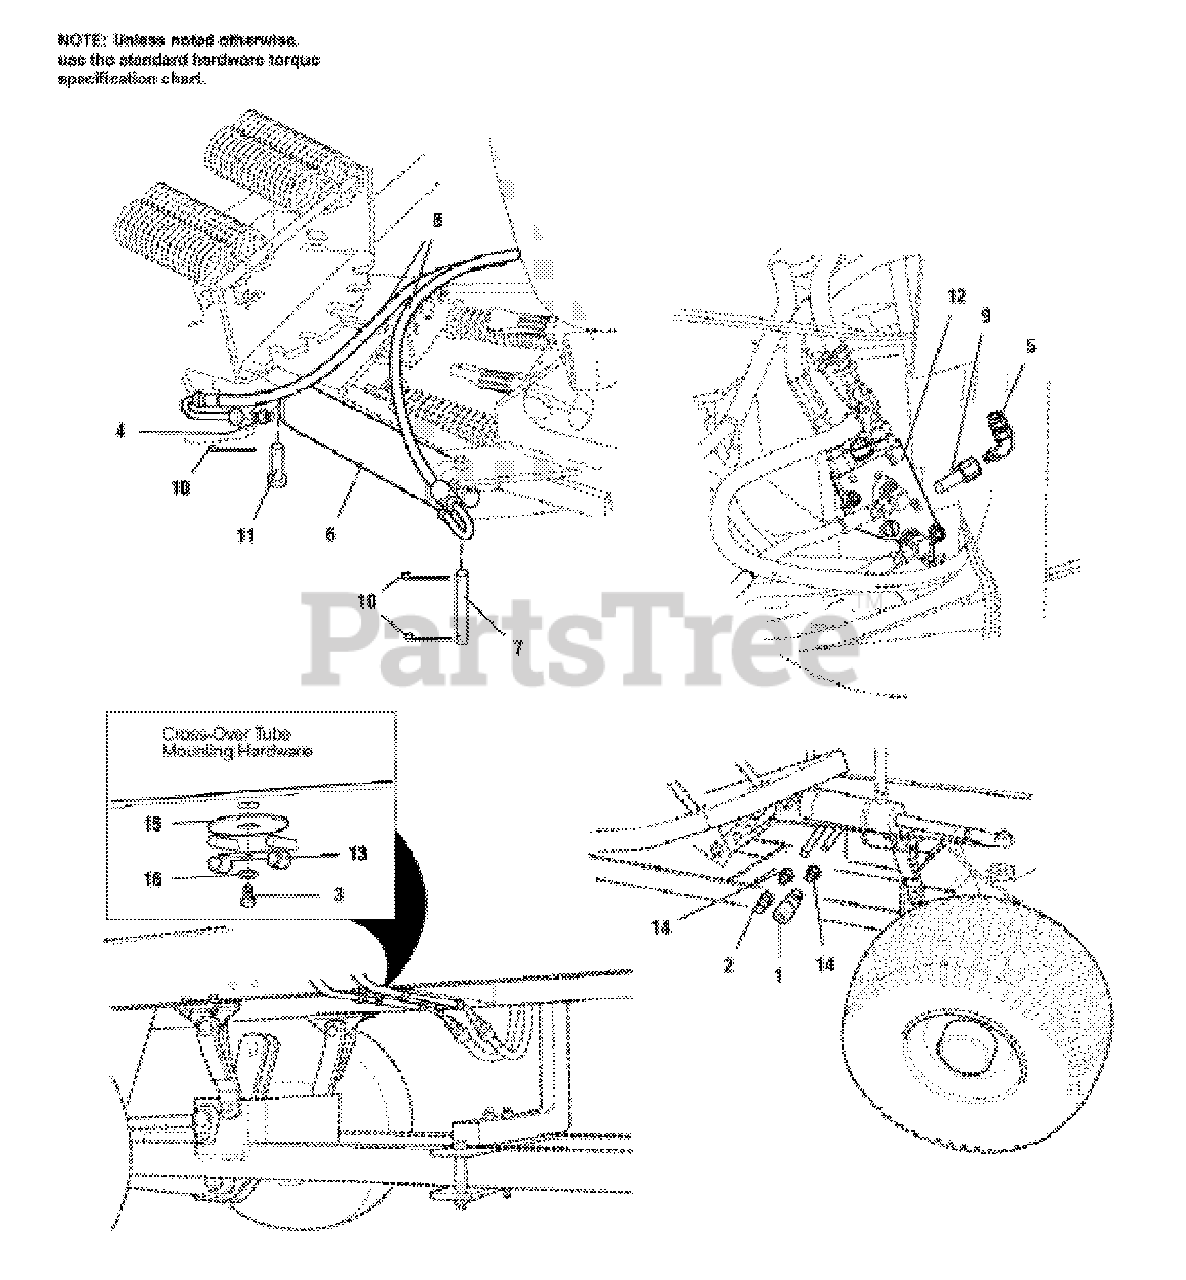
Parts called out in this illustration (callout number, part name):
1	QUICK CONNECTOR, Female Nose Piece Assembly
2	QUICK CONNECTOR, Male Nose Piece Assembly
3	CAPSCREW, Hex Washer Hd, Taptite, 5/16-18 X 1
4	FITTING, Cylinder, Male
5	FITTING, Elbow
6	CYLINDER, Angling
7	PIN, Cylinder, 5/8
8	HOSE, Hydraulic, 1/2" x 28"
9	FITTING, Pressure Beyond Port
10	PIN, Cotter
12	CONTROL VALVE, Single Spool, Power Beyond
13	CLAMP, Metal Cross Over Tube Retaining
14	FITTING, Tube, Male
15	WASHER, 5/16
16	WASHER, Lock, 5/16
